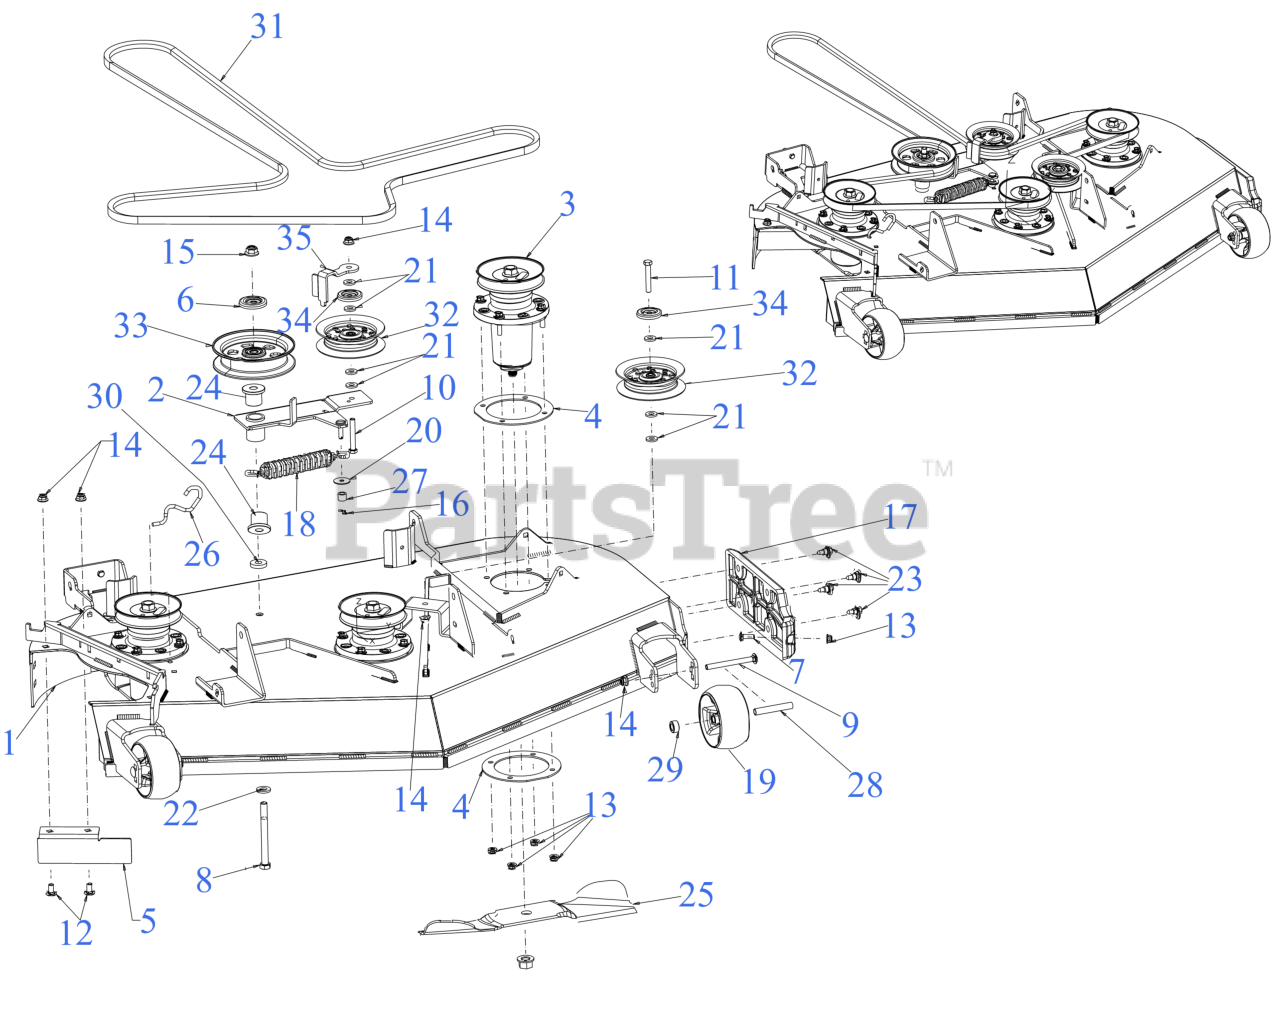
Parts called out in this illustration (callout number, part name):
1	48" FAB DECK SHELL
2	48" DECK IDLER ASSEMBLY
3	SPINDLE ASSEMBLY
4	SPINDLE PLATE
6	PULLEY CAP (.540 x 2.041 DIA)
7	CARRIAGE BOLT 5/16-18 x 1.00
8	BOLT-HEX 1/2-13X5.0 GR5
9	CARRIAGE BOLT 3/8-16 x 4.00 GR5
10	HEX SCREW-3/8-16X2.5 GR5
11	SCREW 3/8-16 x 2.25 GR5
12	CARRIAGE BOLT 3/8-16 x .75
13	FLANGE LOCK NUT 5/16-18
16	BOW TIE COTTER PIN 1/4-5/16
17	DECK SKID PLATE
18	SPRING (1.28" DIA x 8.5" LONG)
19	DECK WHEEL
20	FLAT WASHER .322 ID x 1.25 x .060
21	FLAT WASHER
22	FLAT WASHER .531X1.060X.134
23	SHOULDER SCREW .43X.29X5/16-18 TT
24	FLANGE BEARING
26	DECK SPRING HOOK
28	SPACER .38X.49X3.05LG
29	SPACER-.505 1D
30	SPACER PLATE
31	V-BELT B SEC x 141.50
32	IDLER PULLEY 4.0
33	5" FLAT IDLER PULLEY
34	IDLER PULLEY CAP
35	48" IDLER KEEPER
